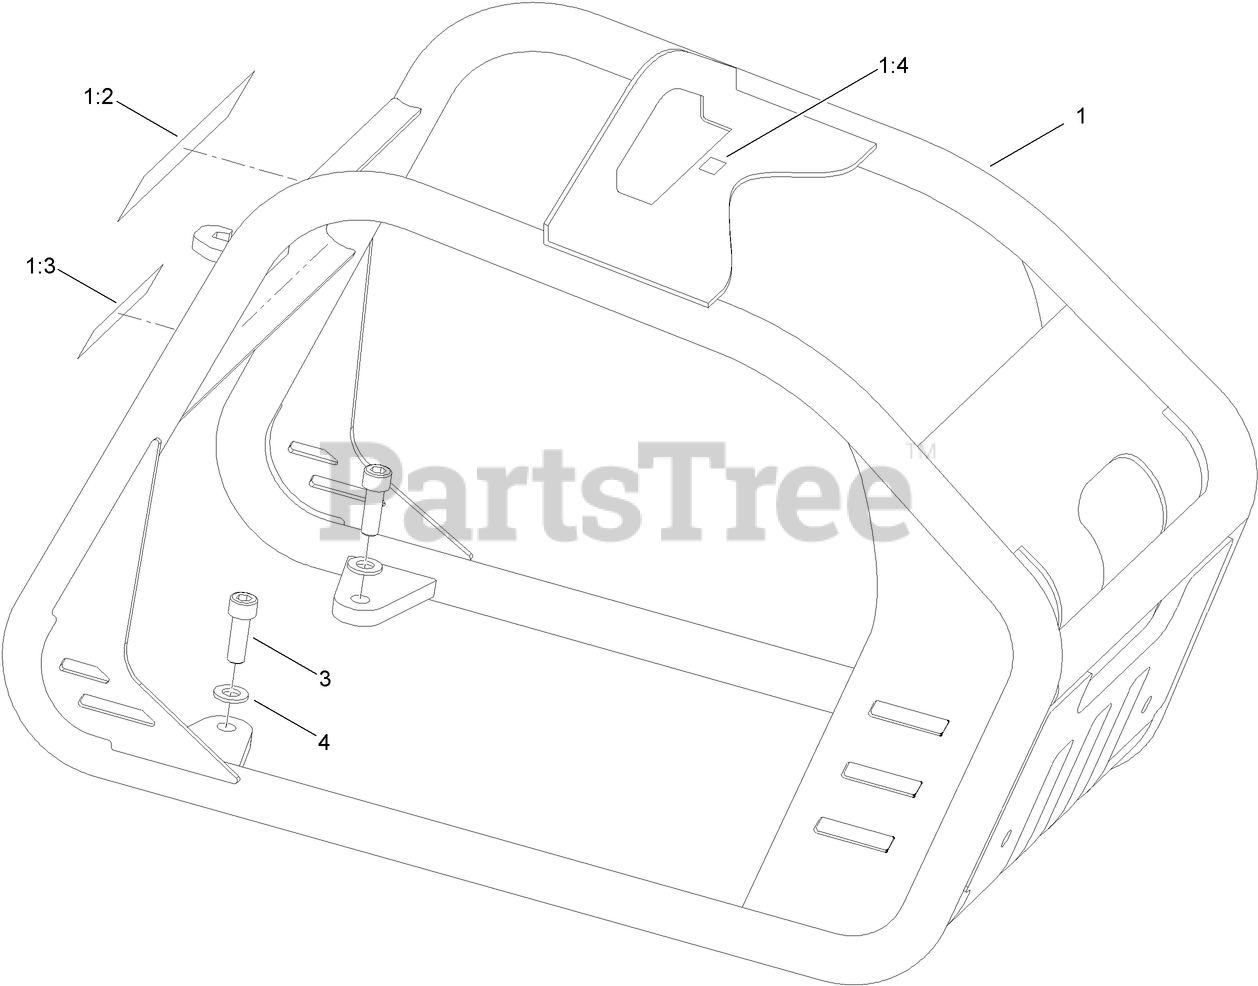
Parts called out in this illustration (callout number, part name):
1	ENGINE CAGE ASM
1:2	DECAL-WARNING, PLATE
1:3	DECAL-ARRESTER, SPARK
1:4	DECAL-POINT, LIFT
4	WASHER
